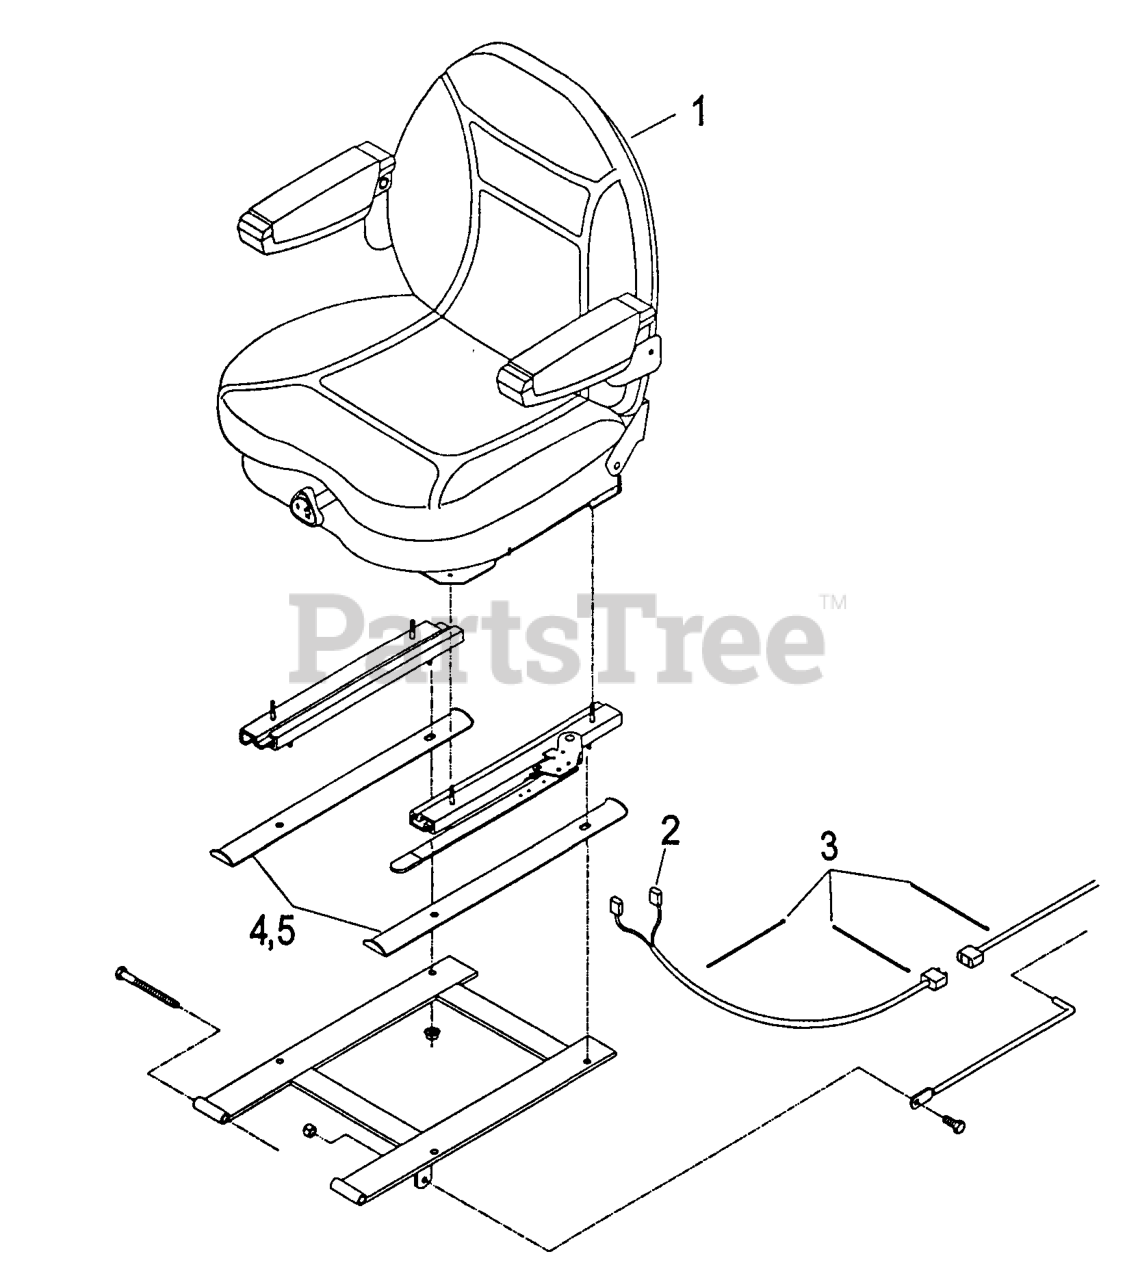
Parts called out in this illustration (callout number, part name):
3	TIE-PLASTIC
4	STOP-SEAT
5	STOP/SPACER-SEAT
